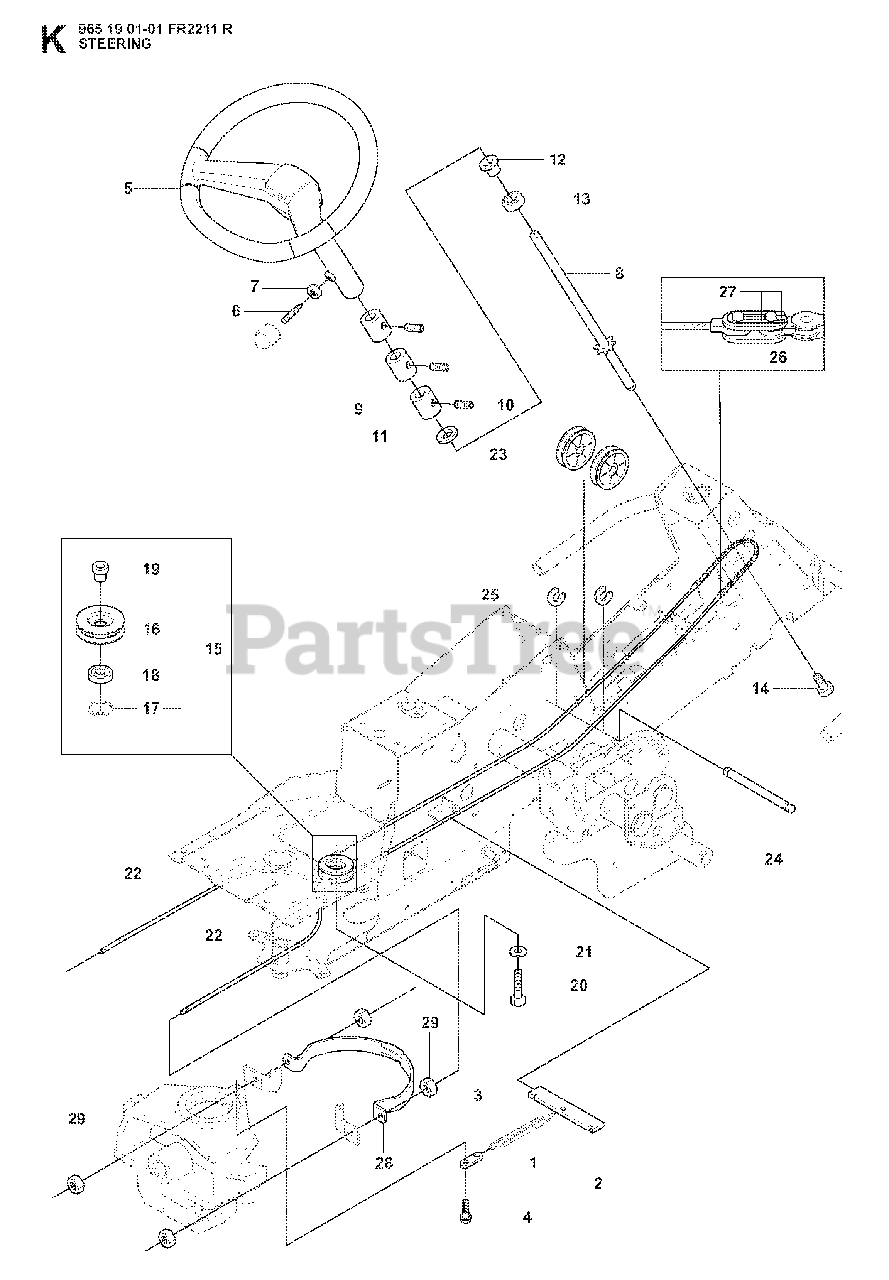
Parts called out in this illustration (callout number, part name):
2	SPRING BRACKET
3	CONNECTOR
5	STEERING WHEEL
7	NUT
8	ROD STEERING ASSY
13	BALL BEARING 6004-2RS1
17	CIRCLIP SGH 47
18	BALL-BEARING 6204-2RS
22	RP STEERING CABLE COMPLETE
25	RETAINING RING
26	STEERING CHAIN
28	WIRE GUIDE
